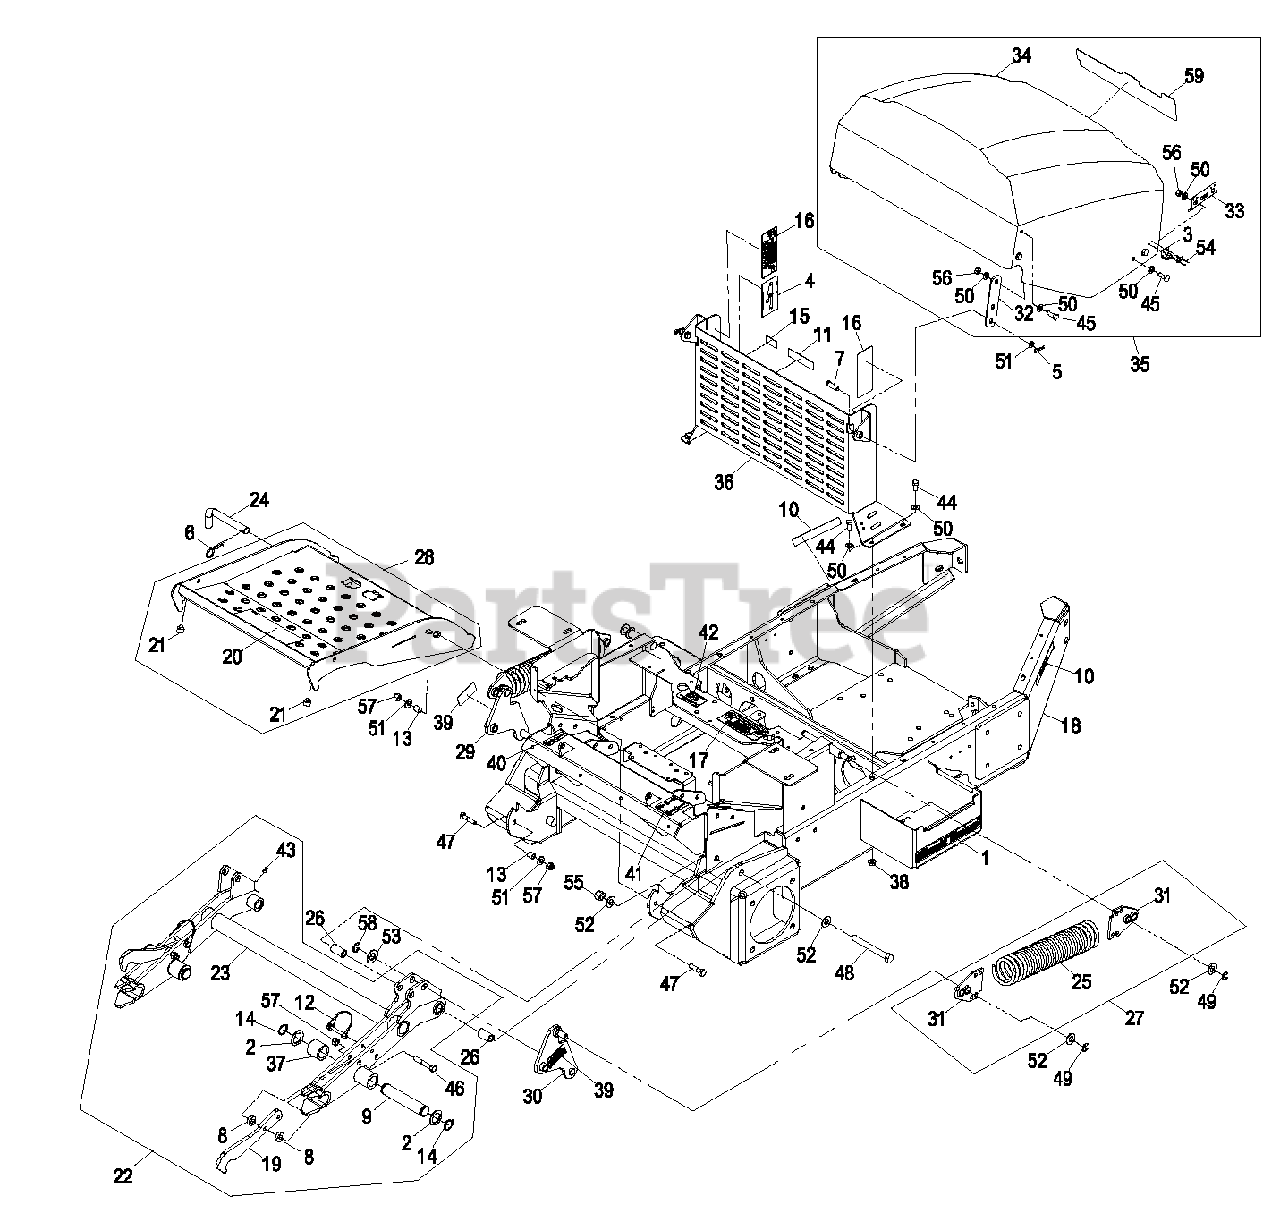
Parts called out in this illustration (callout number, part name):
1	DECAL-BATTERY
2	WASHER-SPACER
4	DECAL-ROUTING, BELT
5	PIN-COTTER
6	PIN-COTTER
7	PIN-CLEVIS
8	SPACER
10	DECAL-WARNING
11	DECAL-COVER, MISSING
12	PIN-HITCH
13	SPACER-TUBE, PUMP LINK
14	RING-RETAINING
16	DECAL-DEVICES, ROTATING
17	DECAL,PUMP FAN WARNING
18	ASM, MAIN FRAME FMZ A/C
19	LATCH, FMZ HITCH (PLATED)
20	DECAL-WARNING
21	BUMPER-RUBBER
22	ASM,HITCH FMZ
24	PIN,FULL FOLD (PLTD)
25	SPRING,EXTENSION (PLATED)
26	BUSHING,HITCH PIVOT
27	ASM,FMZ WT XFR SPRING
29	ASM,FMZ RH SPRING BELLCRA
30	ASM,FMZ LH SPRING BELLCRA
31	WLD,FMZ SPRING ANCHOR (PL
33	HOOK, HOOD
34	DECAL,FRONTRUNNER
35	ASM,FMZ AC HOOD W/DCL COM
36	ASM,FMZ A/C HOOD SUPPORT
37	ROLLER,LOCK LEVER
39	DECAL,SPRING LOADED
40	DECAL-CONTROL, MOTION
41	DECAL,MOTION CNTL/PARK BR
42	DECAL,PUMP DRIVE RELEASE
43	FITTING-GREASE
44	SCREW-HH
45	SCREW-HH
46	SCREW-HH
47	SCREW-HH
48	SCREW-HH
49	RING-RETAINING, EXTERNAL
50	WASHER-PLAIN
51	WASHER-FLAT
52	WASHER-FLAT
53	WASHER-FLAT
55	NUT-LOCK, NI
56	NUT-LOCK, NI
57	NUT-LOCK, NI
59	DECAL,FRONTRUNNER
